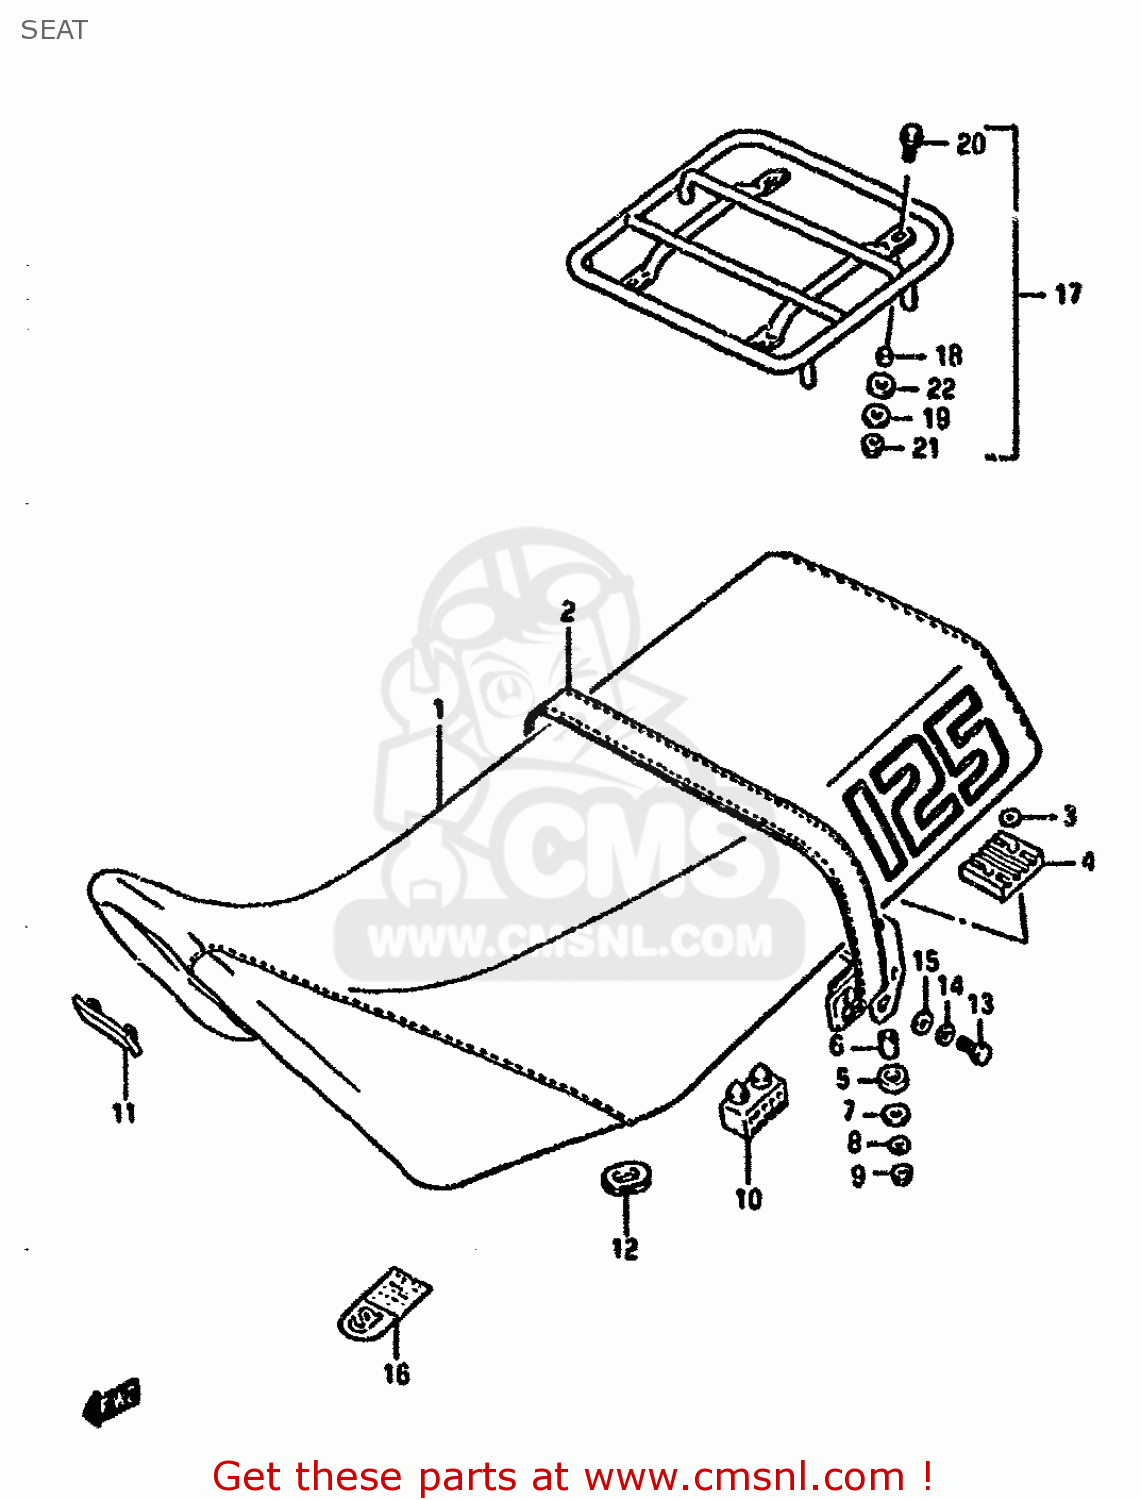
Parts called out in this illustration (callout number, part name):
1	SEAT ASSEMBLY
2	BAND,SEAT
3	WASHER, LOWER
4	CUSHION,FR PLATE
5	CUSHION,SEAT FR
6	SPACER,SEAT SUPPORT
7	WASHER
8	WASHER,LOCK
9	NUT
10	CUSHION,SEAT(40X20X15)
11	CUSHION
12	CUSHION
13	BOLT
14	WASHER,LOCK,8.
15	WASHER
16	LABEL,ASBESTOS WARNING
17	CARRIER SET,SUPPORT
18	SPACER
19	WASHER(6.5X18X1)
20	BOLT
21	NUT 6MM
22	CUSHION
